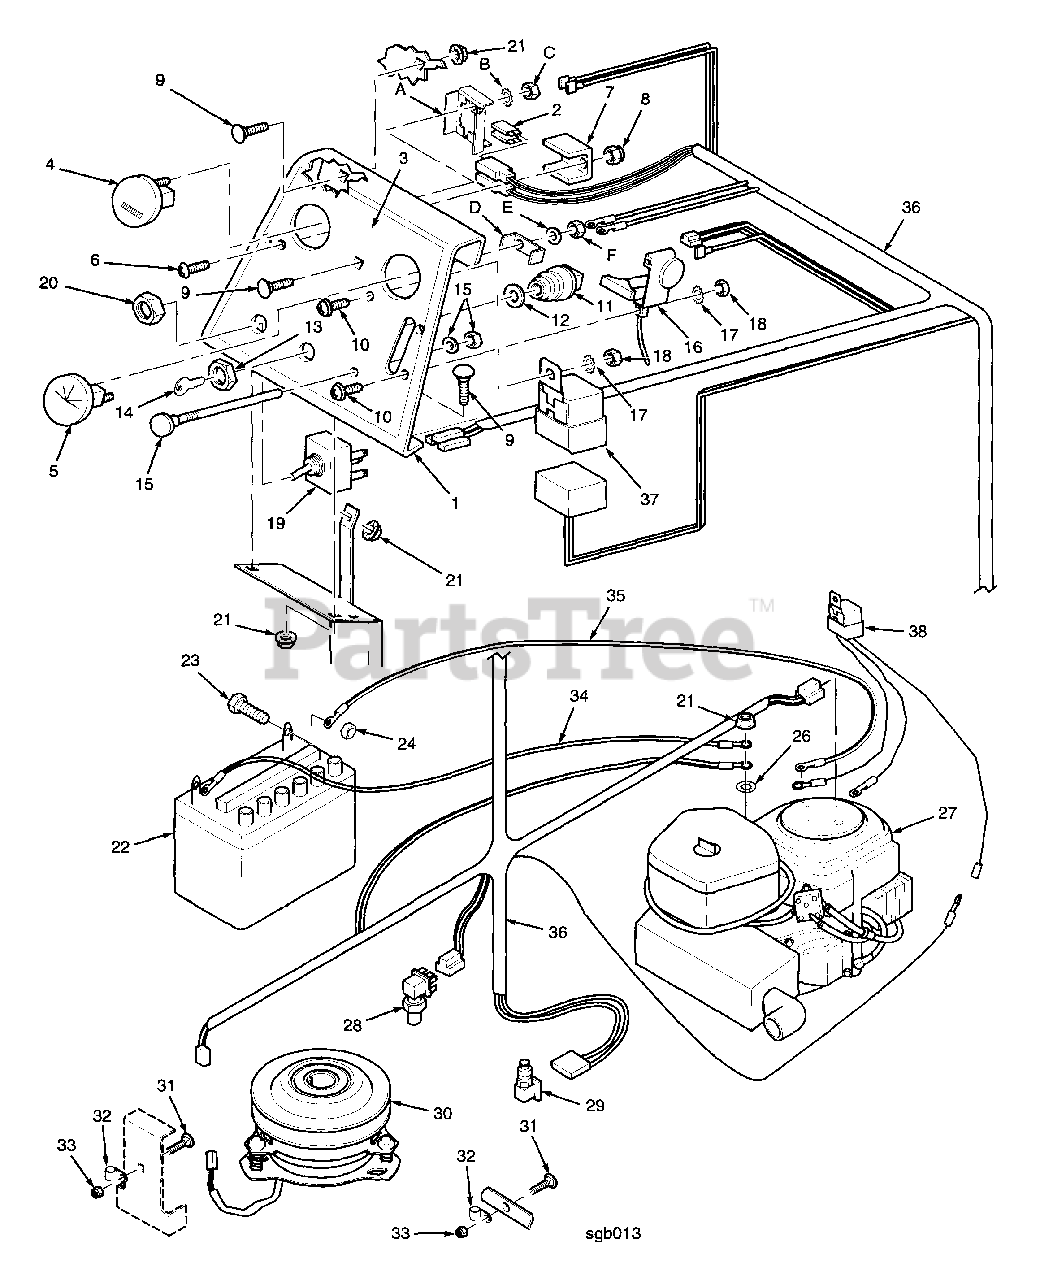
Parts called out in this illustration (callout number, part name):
1	Instrument Panel
2	Blade Fuse, 20 amp.
3	Decal, Instrument Panel
4	Hour Meter
5	Ammeter
6	Phillips Rd. Head Screw, #10-32 x 1-112"
7	Bracket, Fuse Holder
8	Elastic Stop Nut, #10-32
9	Carriage Bolt, 5/16-18 x 3/4"
10	Phillips Washer Head Screw, #10-32 x .50"
11	Keyswitch
12	Lockwasher, 5/8 int. Tooth
14	Ignition Key and Ring Assy.
15	Choke Control
16	Throttle Control
17	Lockwasher, #10 Ext. Tooth
18	Hex Nut, #10-32
19	Switch, PTO
21	Serr. Fl. HH Nut, 5/16-18
22	Battery
23	Bolt, Hex head 1/4-20 x 1/2"
24	Hex Nut 1/4-20
26	Lockwasher 5/16 int. Tooth
27	Engine, 20 HP Kohler CV
28	Switch, Parking Brake
29	Switch, Foot Safety
30	Clutch, Electric
31	Carriage Bolt, 5/16-18 x 3/4"
32	Wireloom
33	Locknut, Elastic Stop 5/16-18
34	Battery Cable, 36" Black
35	Battery Cable, 25" Red
36	Wire Harness, STHM
37	Relay
38	Wire Harness With Relay
A	Hour Meter Bracket
B	Lockwasher, #10 Ext. Tooth
D	Ammeter Bracket
E	Lockwasher, #10 Int. Tooth
